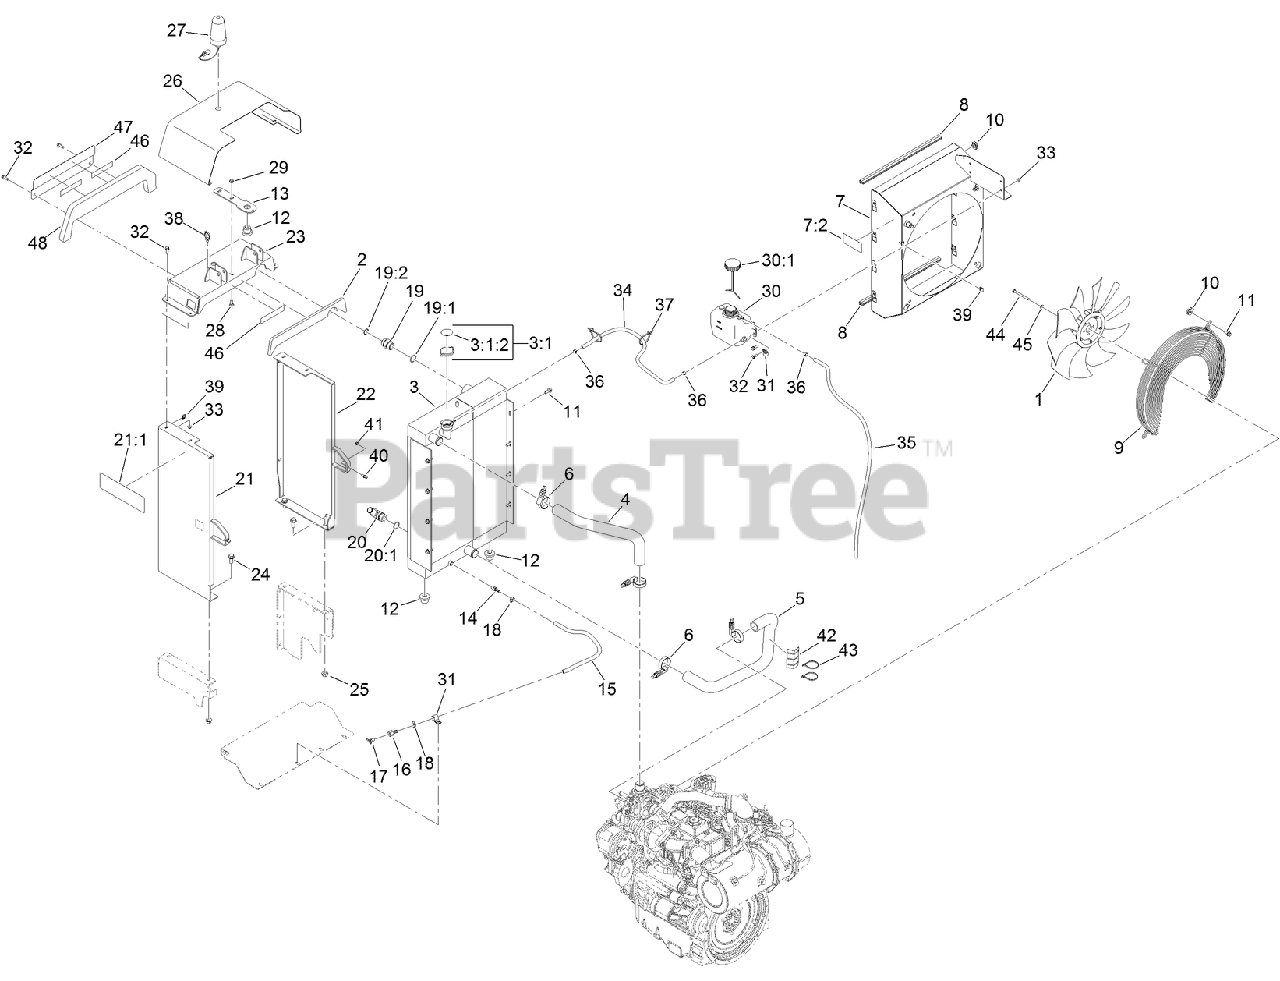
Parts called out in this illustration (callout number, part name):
2	FOAM-RADIATOR
3	COOLER ASM
3:1	RADIATOR CAP ASM
3:1:2	DECAL-DANGER
4	HOSE-RADIATOR, UPPER
5	HOSE-RADIATOR, LOWER
6	CLAMP-TORQUE, CONSTANT
7	FAN SHROUD ASM
7:2	DECAL-ROTATING FAN HAZARD
8	SEAL-BULB
9	GUARD-Fan
10	NUT-TINNERMAN
11	SCREW-HHF
12	MOUNT-ISOLATOR
13	PLATE-SUPPORT, RADIATOR
14	FITTING-STRAIGHT
15	HOSE-OVERFLOW, RADIATOR
16	FITTING-FEMALE, BARBED
17	FITTING-COCK, DRAIN
18	CLAMP-WORM
19	FITTING-STRAIGHT
19:1	O-RING
19:2	O-RING
20	STEM-BARB-90
20:1	O-RING
21	SUPPORT ASM-RADIATOR, RH
21:1	DECAL-SAFETY
22	BRACKET-RADIATOR SUPPORT, LH
23	SUPPORT-RADIATOR
24	SCREW-HHF
25	NUT-LOCK
26	COVER-RADIATOR
27	LIGHT-STROBE
28	SCREW-HH
29	NUT-HF, NI
30	COOLANT RESERVOIR ASM
30:1	CAP-RESERVOIR
31	CLAMP-R
32	SCREW-HHF
33	NUT-HF, NI
34	HOSE-TANK, EXPANSION
35	HOSE-OVERFLOW
36	CLAMP-HOSE
37	TIE-CABLE
38	CLIP-TIE
39	NUT-SPEED
40	STUD-BALL
41	NUT-LOCK, NI
42	PROTECTOR-HOSE
43	TIE-CABLE
44	SCREW-HH
45	WASHER-PLAIN
46	TAPE-DOUBLE STICK
47	PLATE-BLOCKING
48	FOAM-BLOCKING
